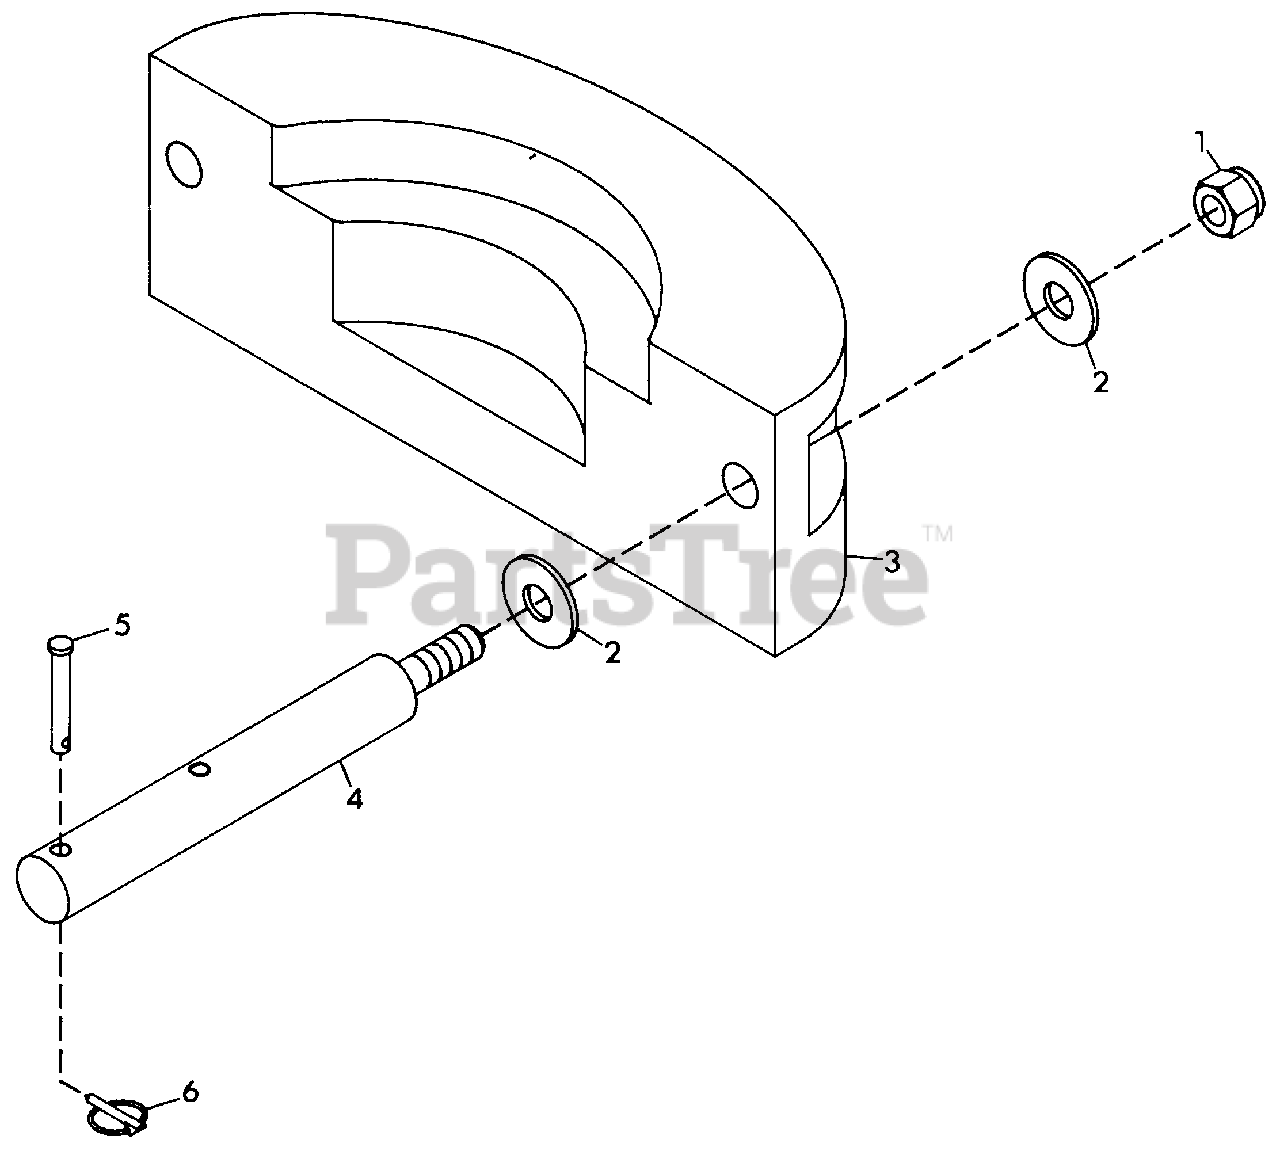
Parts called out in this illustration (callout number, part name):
1	NUT, LOCK 3/4-10
2	WASHER, FLAT .813X2.0X.148
3	WEIGHT, PRO MASTER-50
3	WEIGHT, PRO MASTER-60
4	SHAFT, WEIGHT
5	PIN, CLEVIS .375X2.62
6	PIN, KLIK
